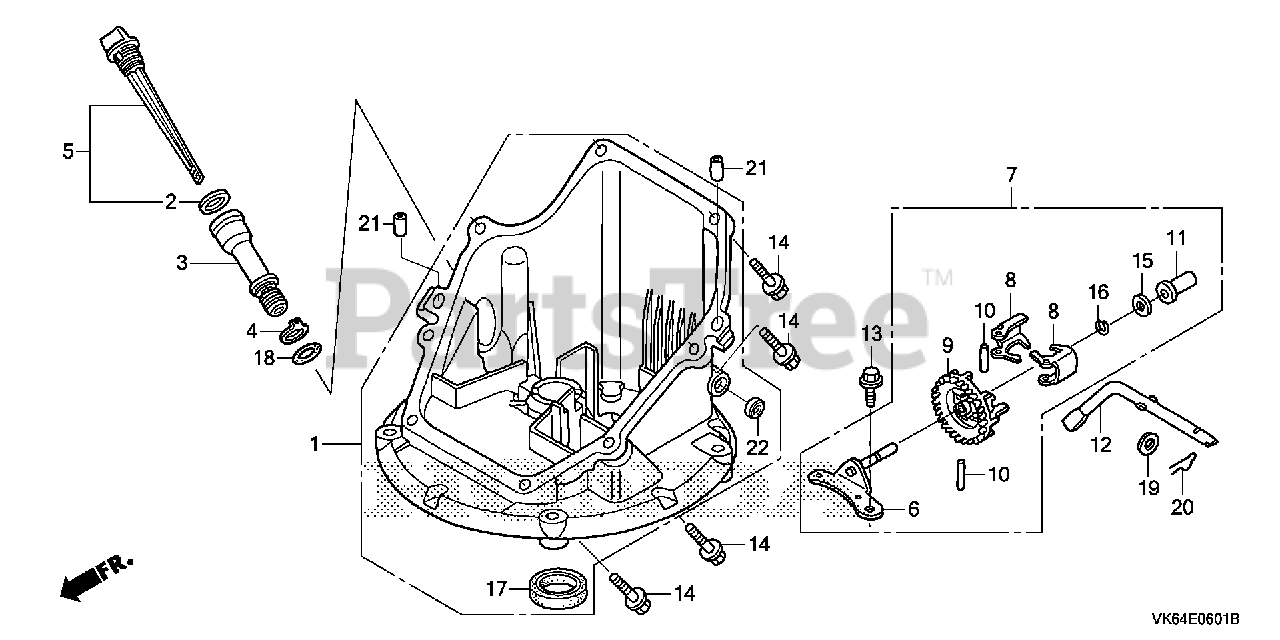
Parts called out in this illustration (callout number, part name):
1	PAN ASSY., OIL
2	GASKET, OIL FILLER CAP Use up to Engine SN 1257294.
3	EXTENSION, OIL FILLER
4	WASHER, EXTENSION LOCK
5	DIPSTICK, OIL
6	SHAFT, GOVERNOR HOLDER
7	GOVERNOR ASSY.
8	WEIGHT, GOVERNOR
9	HOLDER, GOVERNOR WEIGHT
10	PIN, GOVERNOR WEIGHT
11	SLIDER, GOVERNOR
12	SHAFT, GOVERNOR ARM
13	BOLT, FLANGE (6X14)
14	BOLT, FLANGE (6X25) Use up to Engine SN 2056819.
15	WASHER, THRUST (6MM)
16	CLIP, GOVERNOR HOLDER
17	OIL SEAL (28X41.25X6)
18	O-RING (14.8X2.4) (ARAI)
19	WASHER, PLAIN (6MM)
20	PIN, LOCK (8MM)
21	PIN, DOWEL (8X20)
